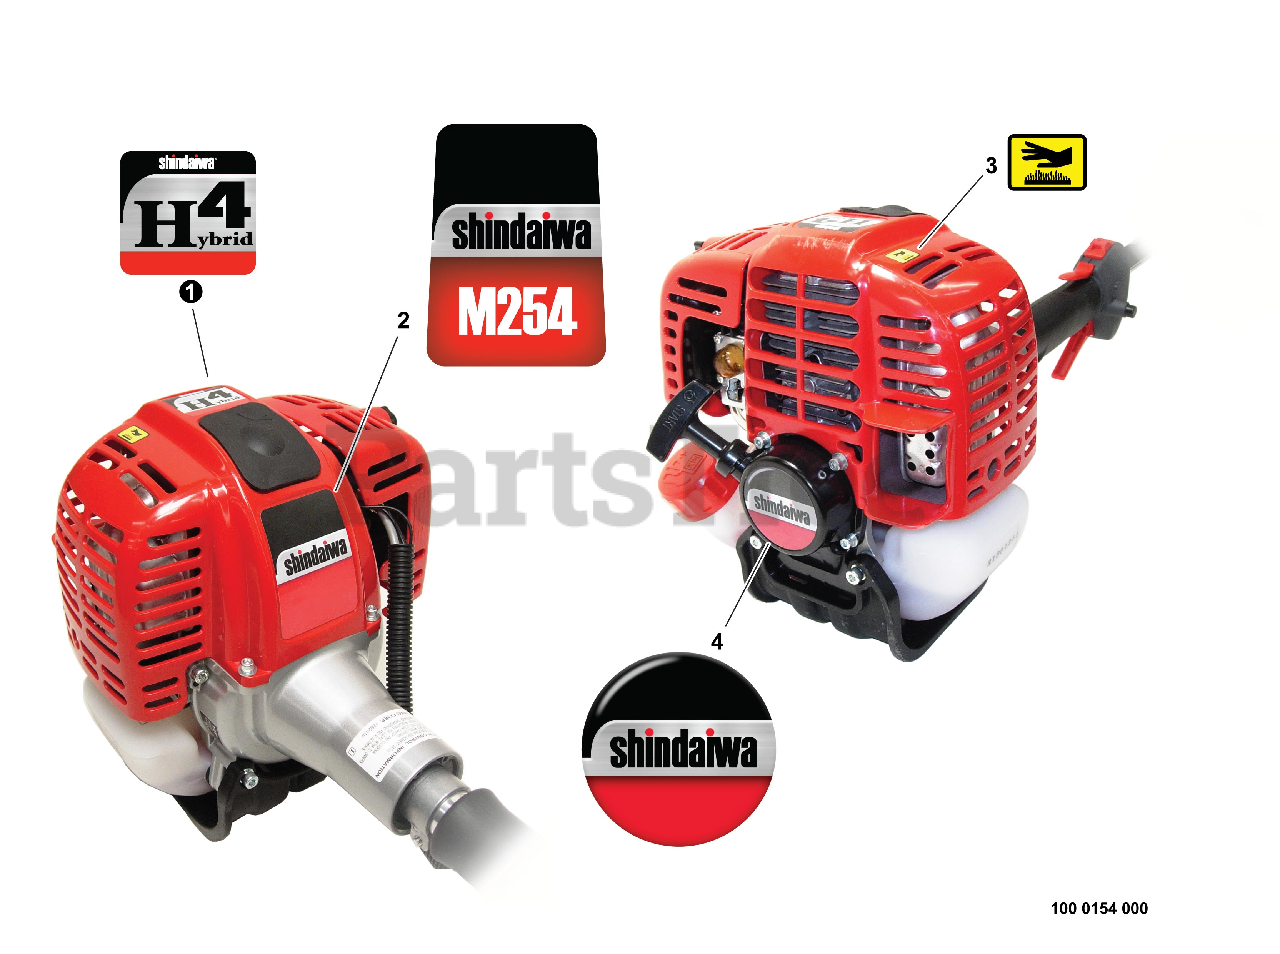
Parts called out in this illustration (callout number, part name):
1	LABEL - H4
2	LABEL - MODEL M254
3	LABEL - HOT SURFACE
4	LABEL - SHINDAIWA
